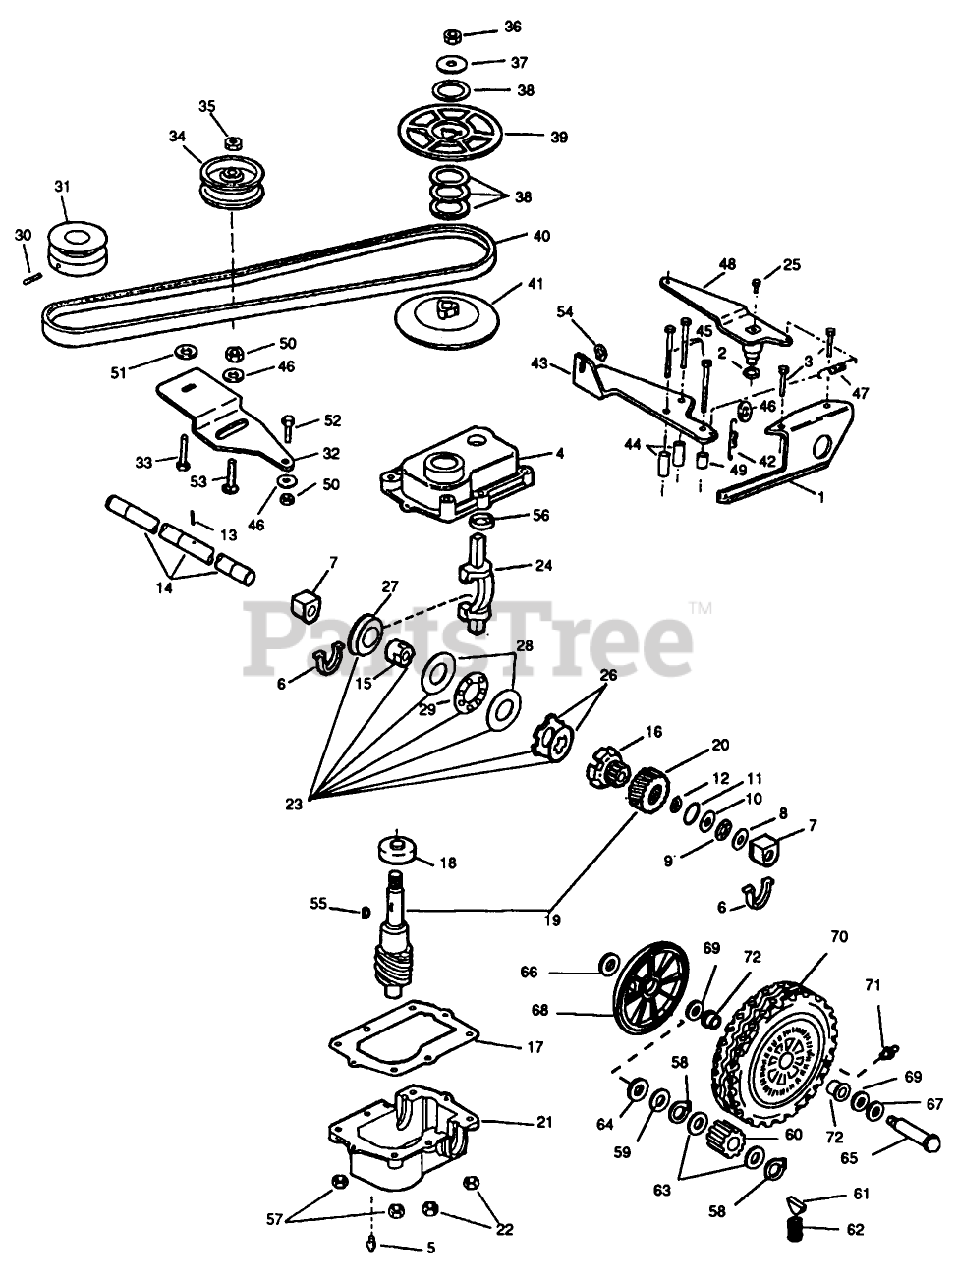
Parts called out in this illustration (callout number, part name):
2	O-RING
7	BEARING & SEAL AY (12)
8	THRUST WASHER
10	WASHER-THRUST
12	RET RING
13	PIN DRIVE LOCK
16	DRIVER BROCKWAY
17	GASKET HOOSIER
18	BEARING-BALL
20	WORM WHEEL
22	LOCKNUT E
24	FORK SHIFT
25	SCREW SEMS SM
26	Disc Plate Kit
27	Collar
30	SET SCREW
31	PULLEY - ENGINE
34	PULLEY IDLER NHI
35	NUT-JAM, LOCKING
36	LOCKNUT
37	WASHER
39	PULLEY UPPER PL
40	V-BELT F
41	PULLEY LOWER PL
42	SPRING EXTEN D&B
43	CONDUIT ANCHOR BRKT
46	WASHER S
47	SPRING
50	NUT-LOCK F
51	WASHER
54	RET. RING
55	KEY GALGER
56	GUIDE ELCO
57	LOCKNUT E
58	RET RING
59	THRUST WASHER
60	PINION BROCKWAY
61	KEY
62	SPRING
63	SPACER/GR ALGHNY
64	WASHER
65	BOLT WHEEL
66	WASHER
67	SPACER
69	WASHER-FELT
71	FITTING LINCOLN
